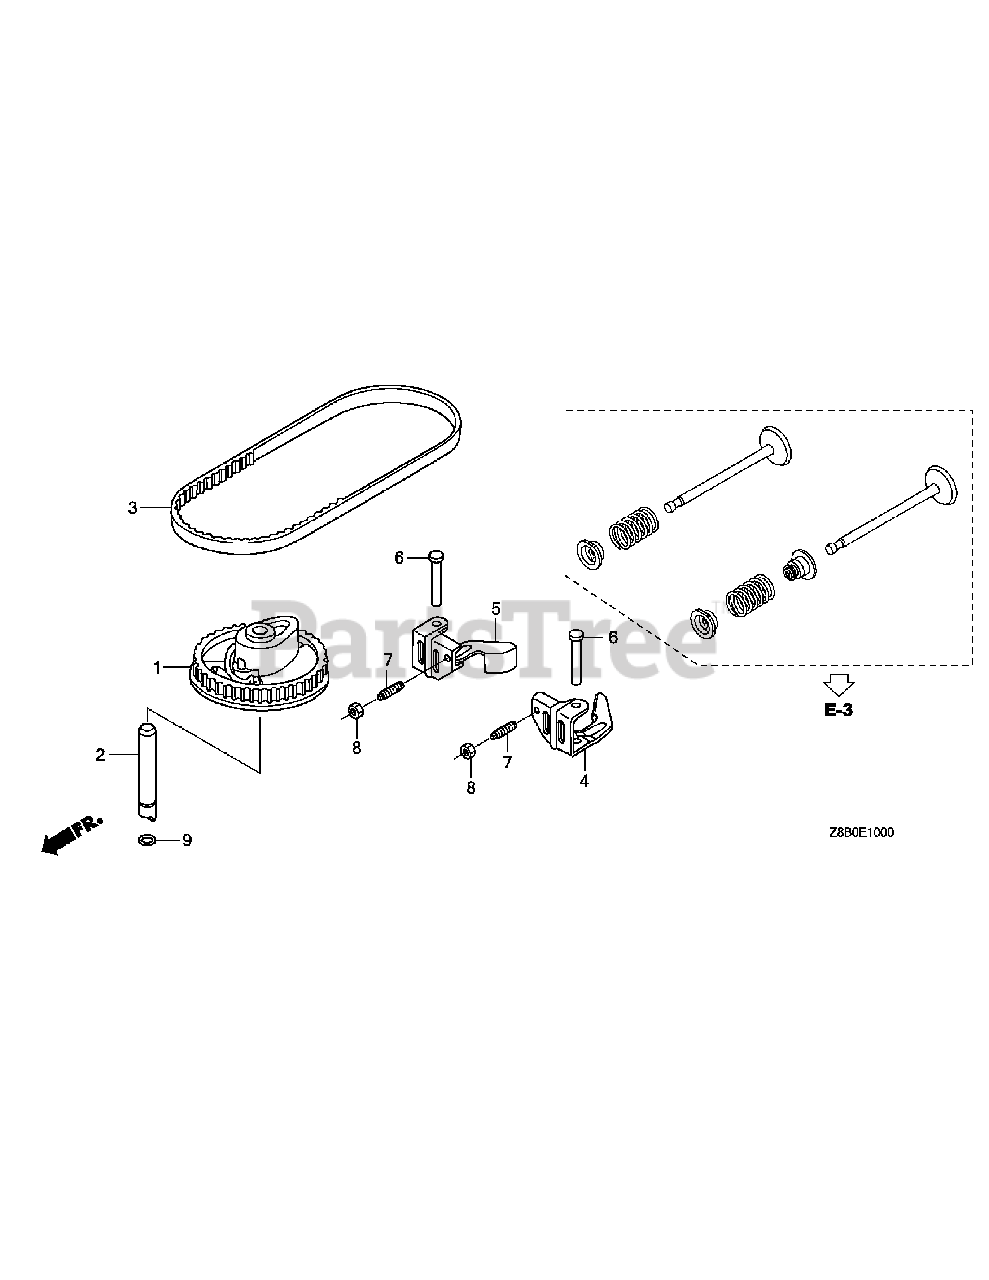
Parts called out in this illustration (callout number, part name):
1	PULLEY COMP., CAMSHAFT
2	SHAFT, CAM PULLEY
3	BELT, TIMING (84HU7 G-200)
4	ARM, IN. VALVE ROCKER
5	ARM, EX. VALVE ROCKER
6	SHAFT, ROCKER ARM
7	SCREW, TAPPET ADJUSTING
8	NUT, TAPPET ADJUSTING
9	O-RING, 6.8X1.9(ARAI)
